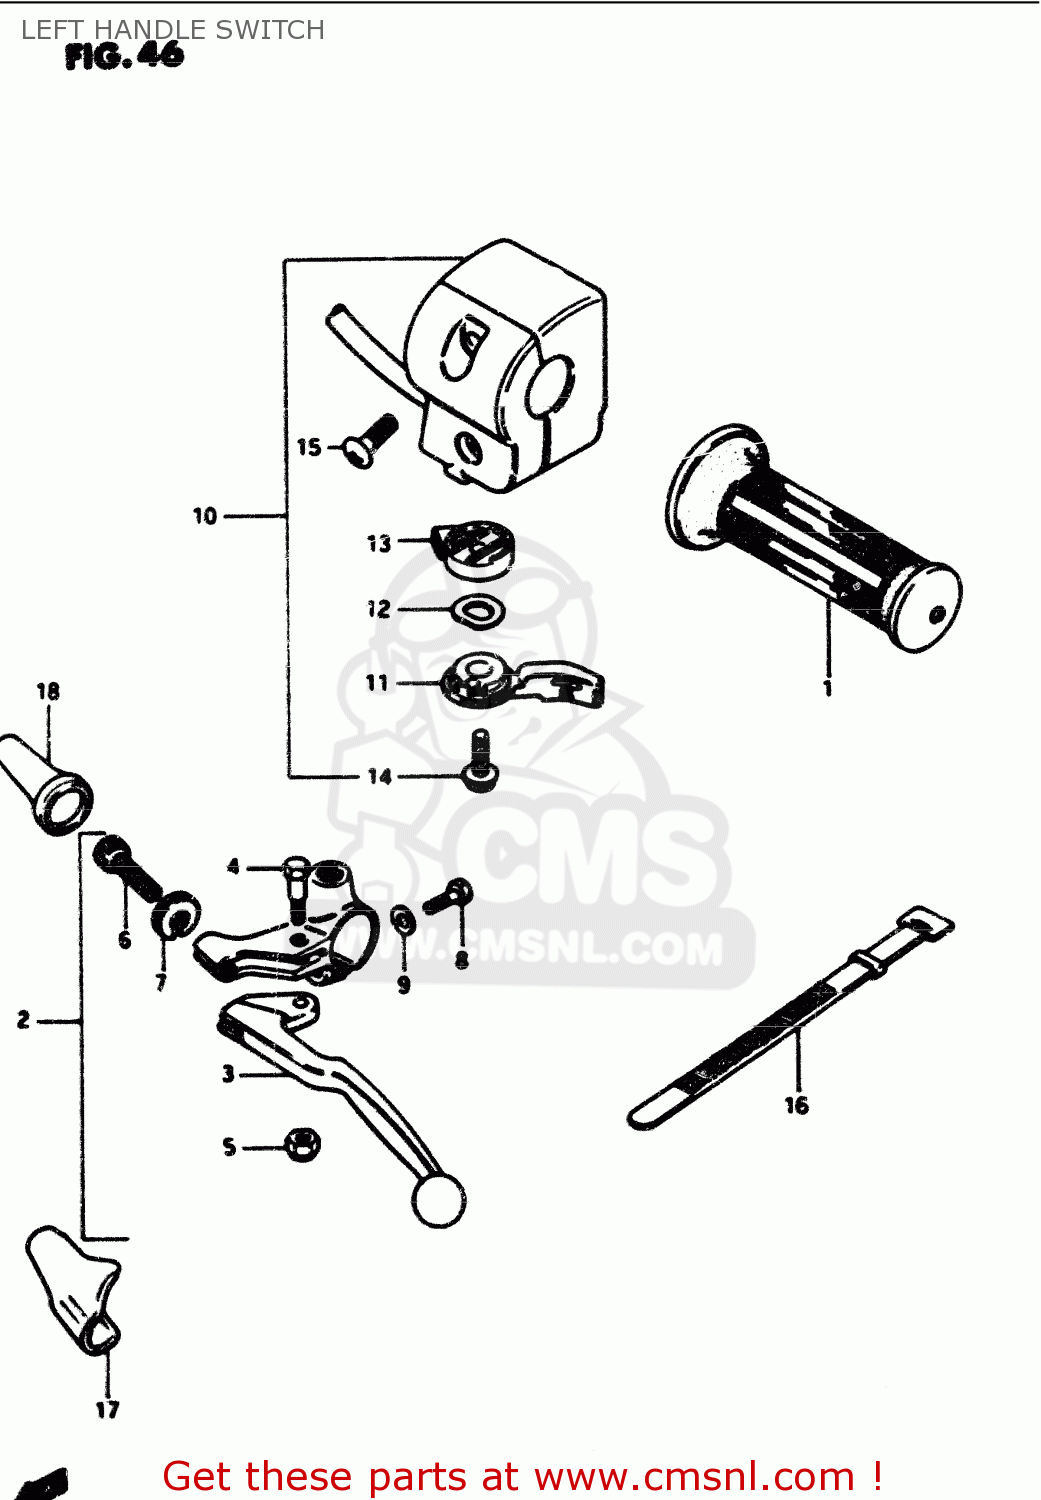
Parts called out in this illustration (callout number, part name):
1	GRIP,L
2	LEVER ASSY, CLUTCH
3	LEVER,CLUTCH
4	BOLT,LEVER PIVOT
5	NUT
6	ADJUSTER,CABLE
7	NUT,CABLE ADJUSTER
8	BOLT
9	WASHER
10	SWITCH ASSY, HANDLE LH (NEUTRAL)
11	LEVER,STARTER
12	WASHER,ADJUSTER
13	BODY,STARTER LEVER
14	SCREW,CHOKE LE
15	SCREW
16	CLAMP(L:120)
17	COVER,CLUTCH LEVER
18	BOOT,CLUTCH CABLE
